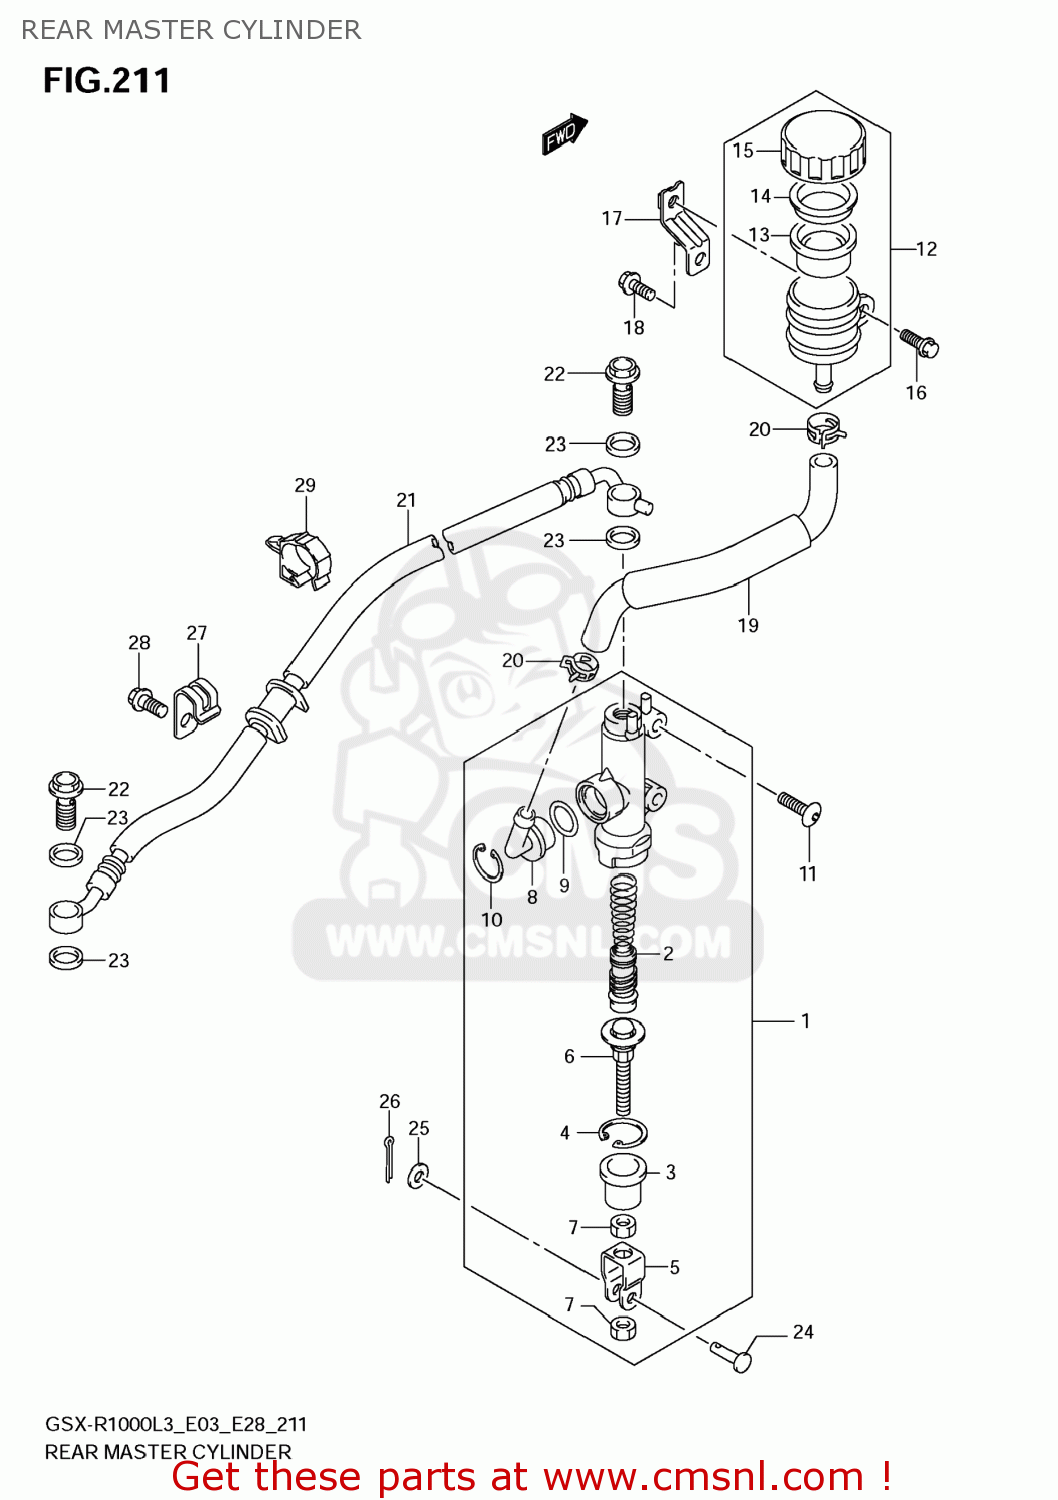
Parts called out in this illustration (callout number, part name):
1	CYLINDER ASSY,RR MASTER
2	PISTON/CUP SET
3	BOOT
4	CIRCLIP
5	YOKE
6	ROD,PUSH
7	NUT
8	CONNECTOR
9	O RING
10	CIRCLIP
11	SCREW(6X20)
12	TANK ASSY,RR RESERVOIR
13	DIAPHRAGM
14	PLATE
15	CAP
16	BOLT
17	BRACKET,RR RESERVOIR TANK
18	BOLT
19	HOSE,RR RESERVOIR TANK
20	CLIP
21	HOSE,RR BRAKE
22	BOLT UNION
23	WASHER(10X15X1.5)
24	PIN(6X18.2)
25	WASHER
26	PIN
27	CLAMP,RR BRAKE HOSE
28	BOLT
29	CLAMP
